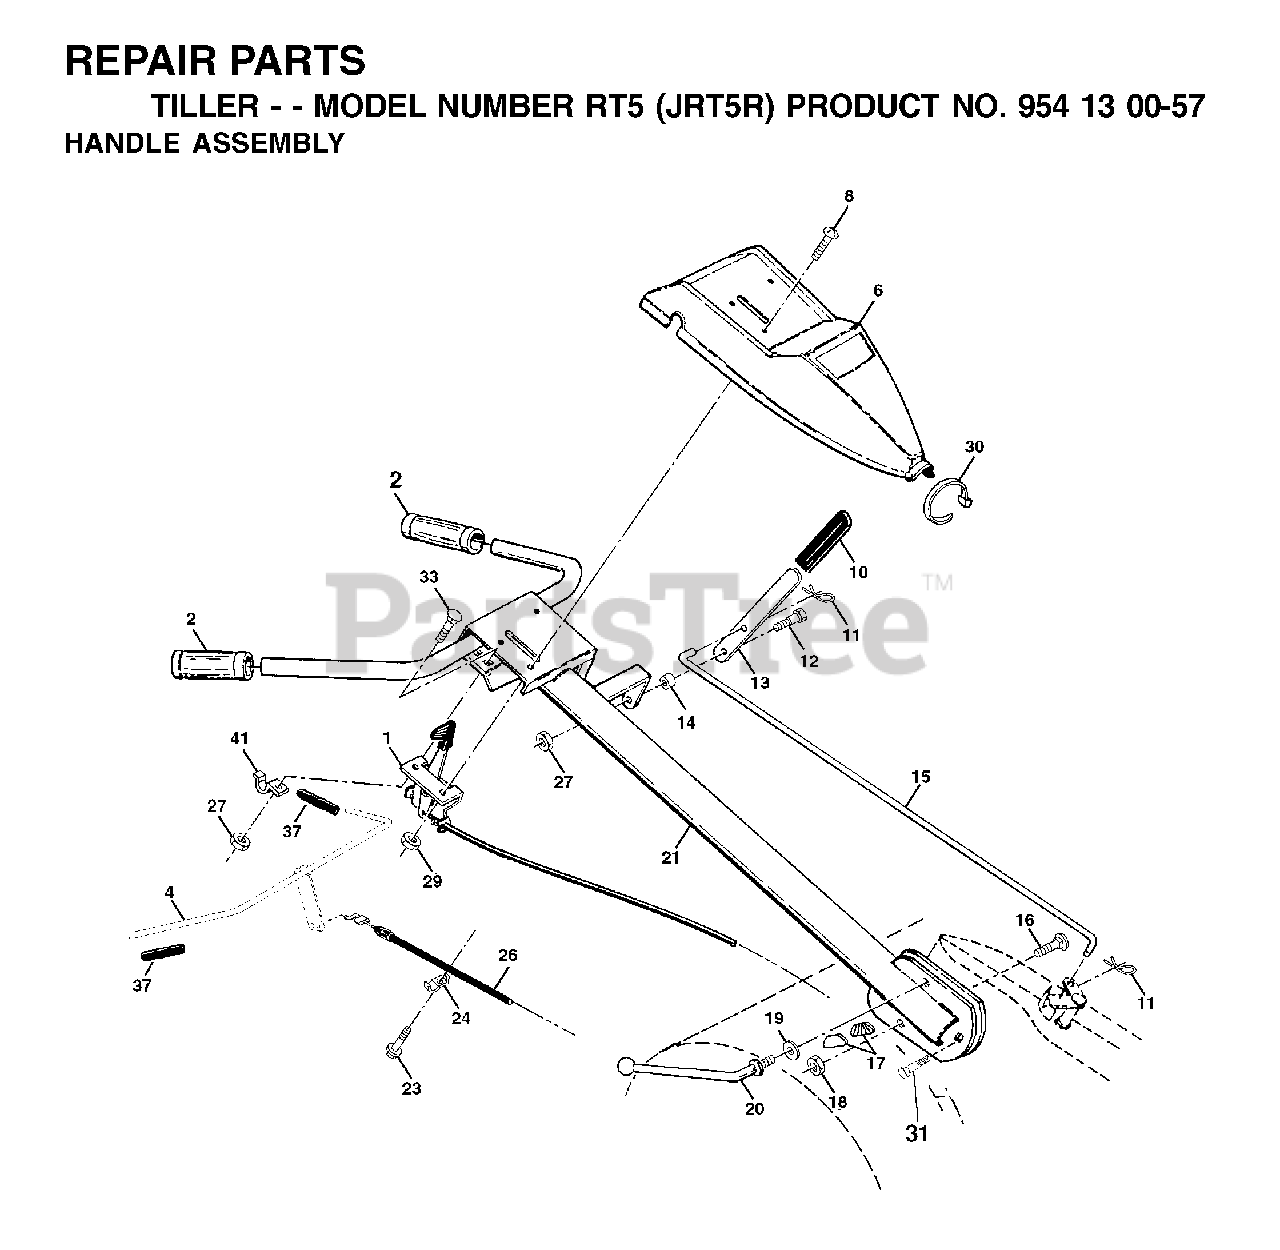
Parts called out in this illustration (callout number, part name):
1	THROTTLE CONTROL CRT
2	GRIPS (2EACH)
4	CONTROL BAR ASSY
8	SCREW.PNHD.10-24
10	GRIP T
11	RETAINER M
12	SHOULDER BOLT ST
13	SHIFT HANDLE CRT
14	GROMMET.RUBBER.CRT.TILLER
15	SHIFT ROD CRT
18	LOCKNUT
19	WASHER CRT
20	LEVER.LOCK.CRT
23	TAPPING SCREW
24	CONDUIT CLIP T
26	CABLE.CLUTCH
27	NUT T
29	NUT **
30	TIE CABLE CRT
31	BOLT.PIVOT
37	GRIP BAR CRT(1)
41	CLAMP.BAR.CRT.BLACK
